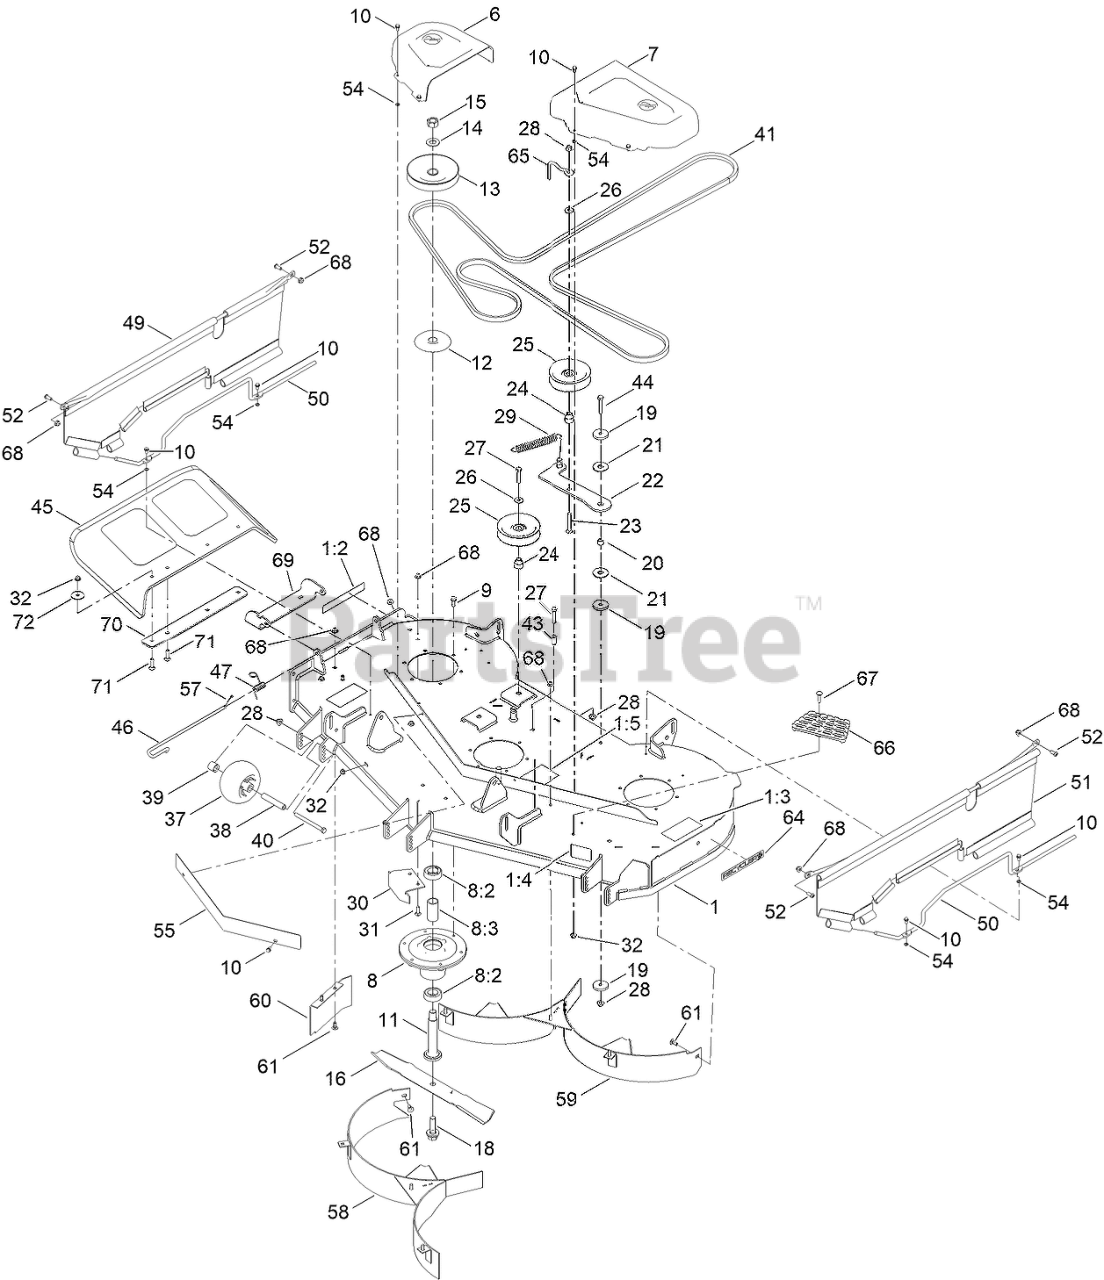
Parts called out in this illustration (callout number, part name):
1	54in DECK ASM
1:2	DECAL-DANGER
1:3	DECAL-DANGER, DECK
1:4	DECAL-SCALP, ANTI
1:5	DECAL-ROUTING, BELT
6	COVER-BELT, RH
7	COVER-BELT, LH
8	SPINDLE ASM
8:2	BEARING-BALL
8:3	SPACER-BEARING
9	SCREW-TAPTITE
10	SCREW-HWH
11	SHAFT-SPINDLE
12	SHIELD-BEARING
13	PULLEY
14	WASHER
15	NUT-HEX
16	BLADE-MULCH, 18.75 INCH
18	SCREW-BLADE
19	WASHER-PLAIN
20	SPACER
21	WASHER-FRICTION, COMPOSITE
22	IDLER ARM ASM
23	SCREW-CARR
24	BUSHING-IDLER
25	PULLEY-IDLER, FLAT
26	WASHER-HARDENED
27	SCREW-HH
28	NUT-HF, NI
29	SPRING-EXTENSION
30	BAFFLE-CUTOFF
31	SCREW-CARR
32	NUT-HF
37	ROLLER-SCALP, ANTI
38	TUBE-SPANNER
39	SPACER-AXLE, REAR
40	SCREW-HH
41	V-BELT
43	SPACER-FENDER
44	HHCS 3/8-16 X 2, GR5, CZ
45	DEFLECTOR
46	PIN-CHUTE
47	SPRING-TORSION
49	ROD SUPPORT, UPPER
50	ROD SUPPORT, LOWER
51	SIDE GUARD ASM
52	SCREW-HSBH
54	NUT-RETAINING
55	SHIELD-FRONT
57	PIN-COTTER
58	BAFFLE-RECYCLER
59	BAFFLE-RECYCLER, LH
60	GUARD-BAFFLE
61	BOLT-CARR
64	DECAL-RECYCLER
65	GUIDE-BELT, IDLER
66	STEP-DECK
67	BOLT-CARRIAGE
68	NUT-HF
69	BRACKET-DEFLECTOR, UPPER
70	PLATE-DEFLECTOR
71	BOLT-CARRIAGE
72	WASHER-FLAT
